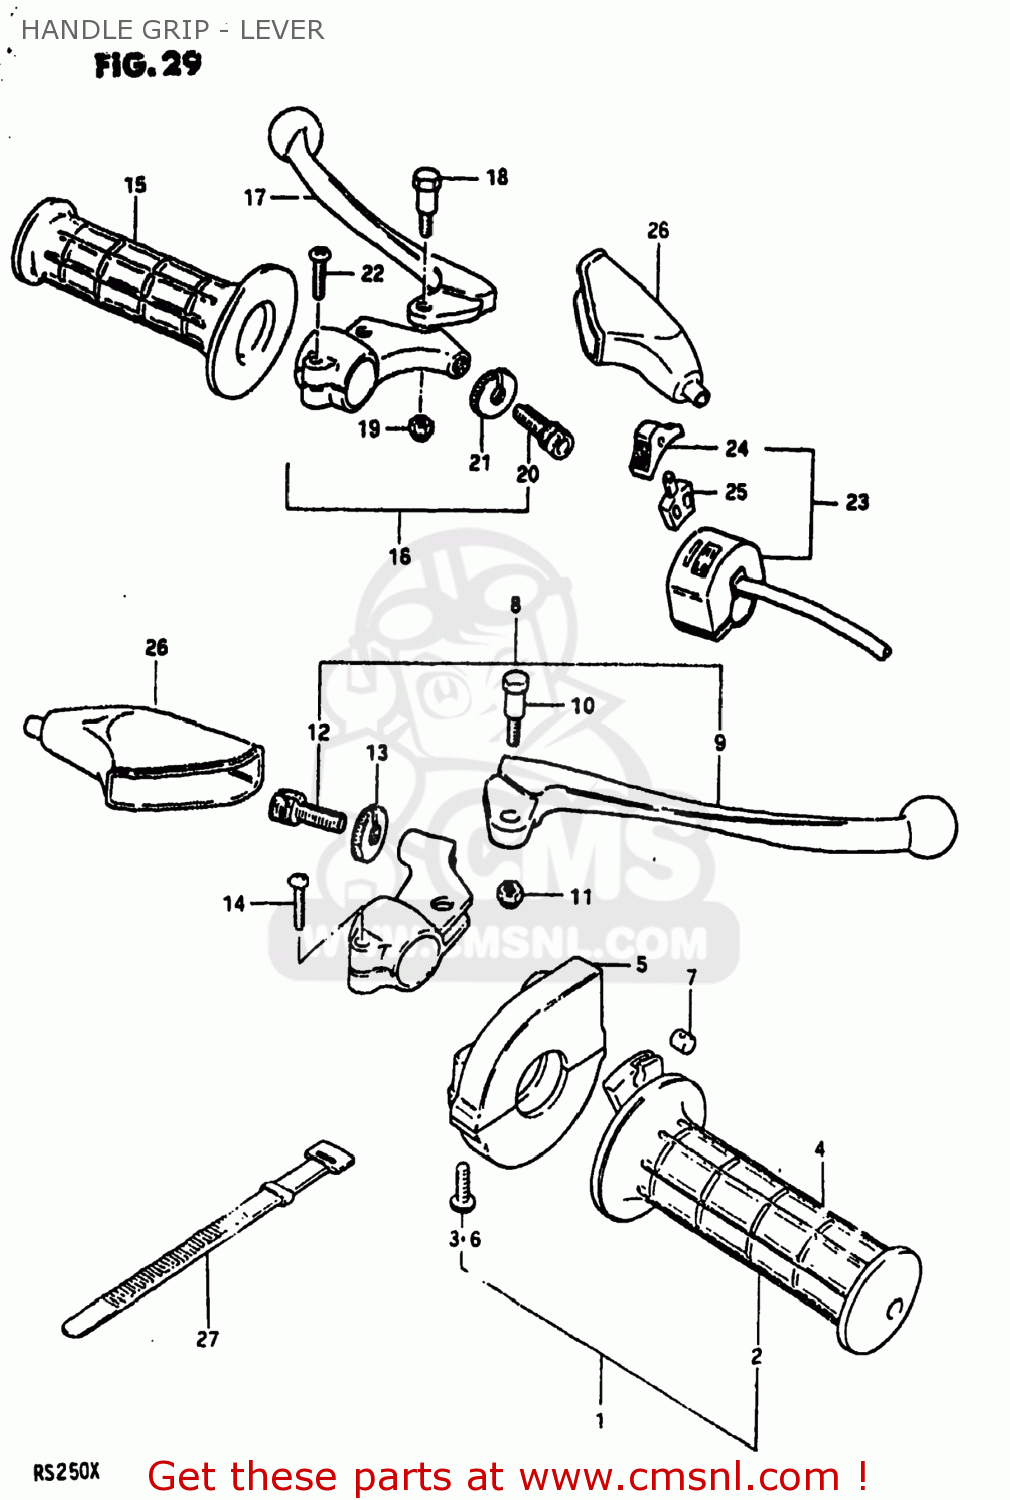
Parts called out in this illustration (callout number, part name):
1	CASE ASSEMBLY,THROTTLE
2	GRIP,THROTTLE
3	SCREW
4	GRIP,THROTTLE
5	CASE,THROTTLE
6	SCREW
7	PIECE,THROTTLE END
8	LEVER ASSY,BRAKE
9	LEVER,BRAKE
10	BOLT,LEVER
11	NUT 6MM
12	ADJUSTER,CABLE
13	NUT,CABLE ADJUSTER
14	SCREW
15	GRIP,LEFT
16	LEVER ASSY,CLUTCH
17	LEVER,CLUTCH
18	BOLT,LEVER
19	NUT 6MM
20	ADJUSTER,CABLE
21	NUT,CABLE ADJUSTER
22	SCREW
23	SWITCH,DIMMER
24	KNOB,LIGHTING & DIMMER
25	BLOCK,LIGHTING/DIMMER
26	COVER,CLUTCH LEVER
27	CLAMP(L:120)
